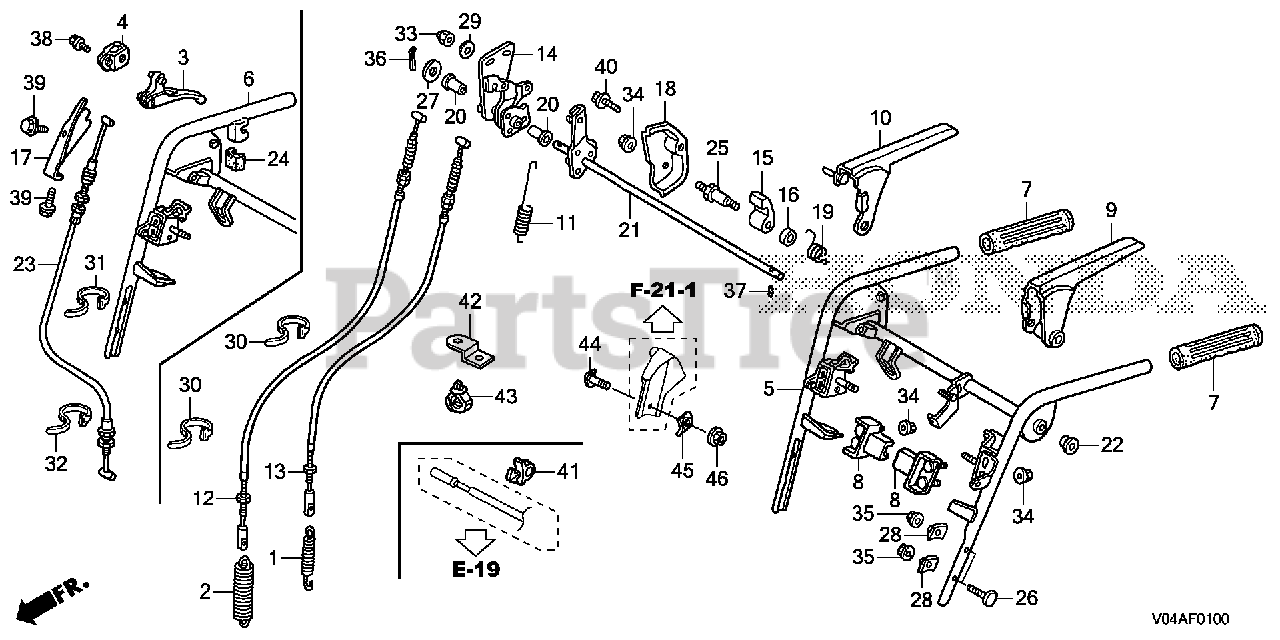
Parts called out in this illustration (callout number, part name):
1	SPRING, TENSIONER ROLLER
2	SPRING, TENSIONER ROLLER (AUGER)
5	PIPE, HANDLE (UPPER)
7	GRIP, HANDLE
8	STOPPER, CHANGE LEVER
9	LEVER, CLUTCH
10	LEVER, AUGER CLUTCH
11	SPRING, CLUTCH LEVER
12	CABLE, CLUTCH
13	CABLE, CLUTCH
14	BOSS, CAM LOCK
15	RATCHET, LEVER
16	COLLAR, RATCHET
18	COVER, RATCHET
19	SPRING, RATCHET
20	BUSH (13X22.5) (GRAY)
21	SHAFT, CLUTCH LEVER
22	BUSH (14MM)
25	BOLT, PIVOT (6MM)
26	BOLT, HANDLE HOLDER
27	WASHER, THRUST (10MM)
28	WASHER, FRAME JOINT
29	WASHER (6MM)
30	BAND, WIRE (95MM)
33	NUT, CAP (6MM)
34	NUT, FLANGE (6MM)
35	NUT, FLANGE (8MM)
36	PIN, SPLIT (3.0X18)
37	PIN, SPRING (4X16)
40	BOLT, FLANGE (6X10)
41	CLIP, IGNITION WIRE (8MM)
